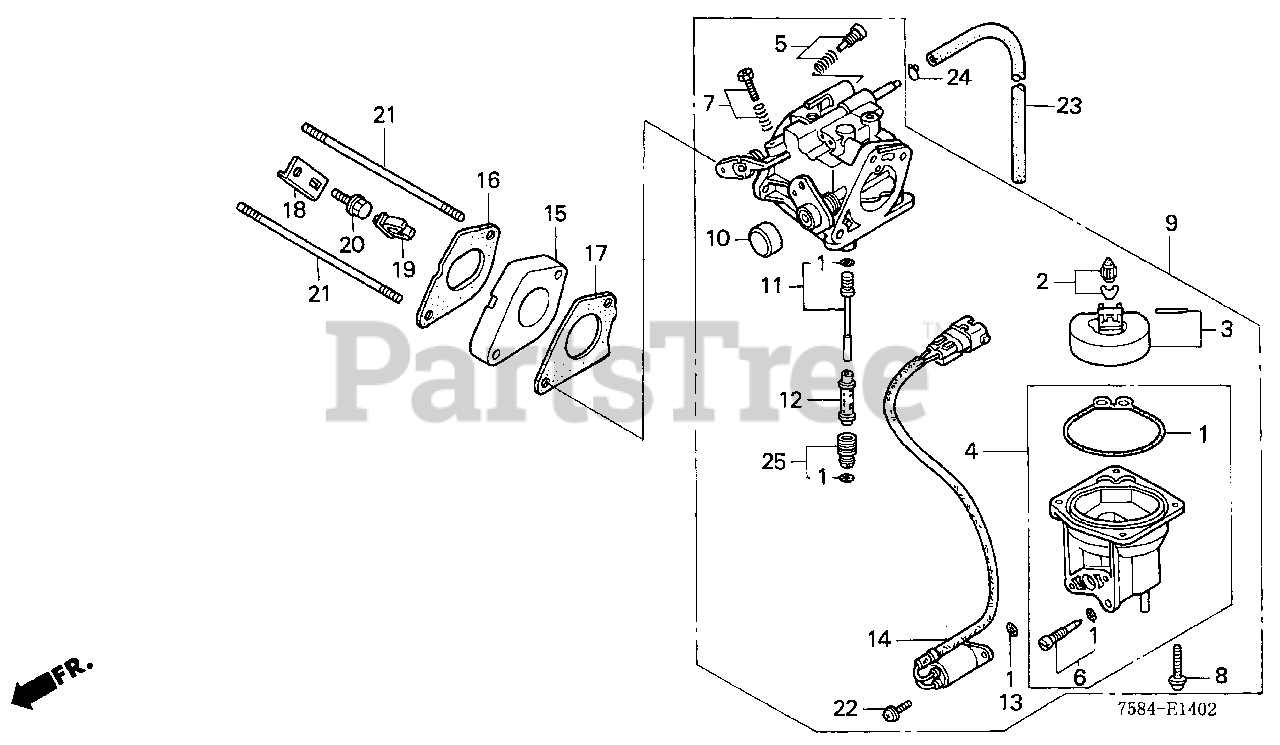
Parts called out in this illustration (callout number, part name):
1	GASKET SET
2	VALVE SET, FLOAT
4	CHAMBER SET, FLOAT
6	SCREW SET, DRAIN
8	SCREW-WASHER
9	CARBURETOR ASSY. (BG17B A)
9	CARBURETOR ASSY. (BG17A B)
10	CAP, CHOKE LEVER DUST
11	JET SET (#50)
12	NOZZLE, MAIN
13	O-RING (5.8X1.9)
14	VALVE ASSY., SOLENOID
15	INSULATOR, CARBURETOR
16	GASKET, INSULATOR
17	GASKET, CARBURETOR
18	BRACKET, HARNESS CLIP
19	CLIP B, AIR TEMPERATURE SWITCH WIRE
20	BOLT, FLANGE (6X14)
21	BOLT, STUD (6X113)
22	SCREW-WASHER (5X12)
23	BULK HOSE, FUEL (4.5X3000) (4.5X380)
24	CLIP, TUBE (B8)
25	JET SET, MAIN (#88) Use up to Engine SN BG17A A.
25	JET SET, MAIN (#90)
25	JET SET, MAIN (#92)
25	JET SET, MAIN (#92) Use from Engine SN BG17A B.
25	JET SET, MAIN (#95)
